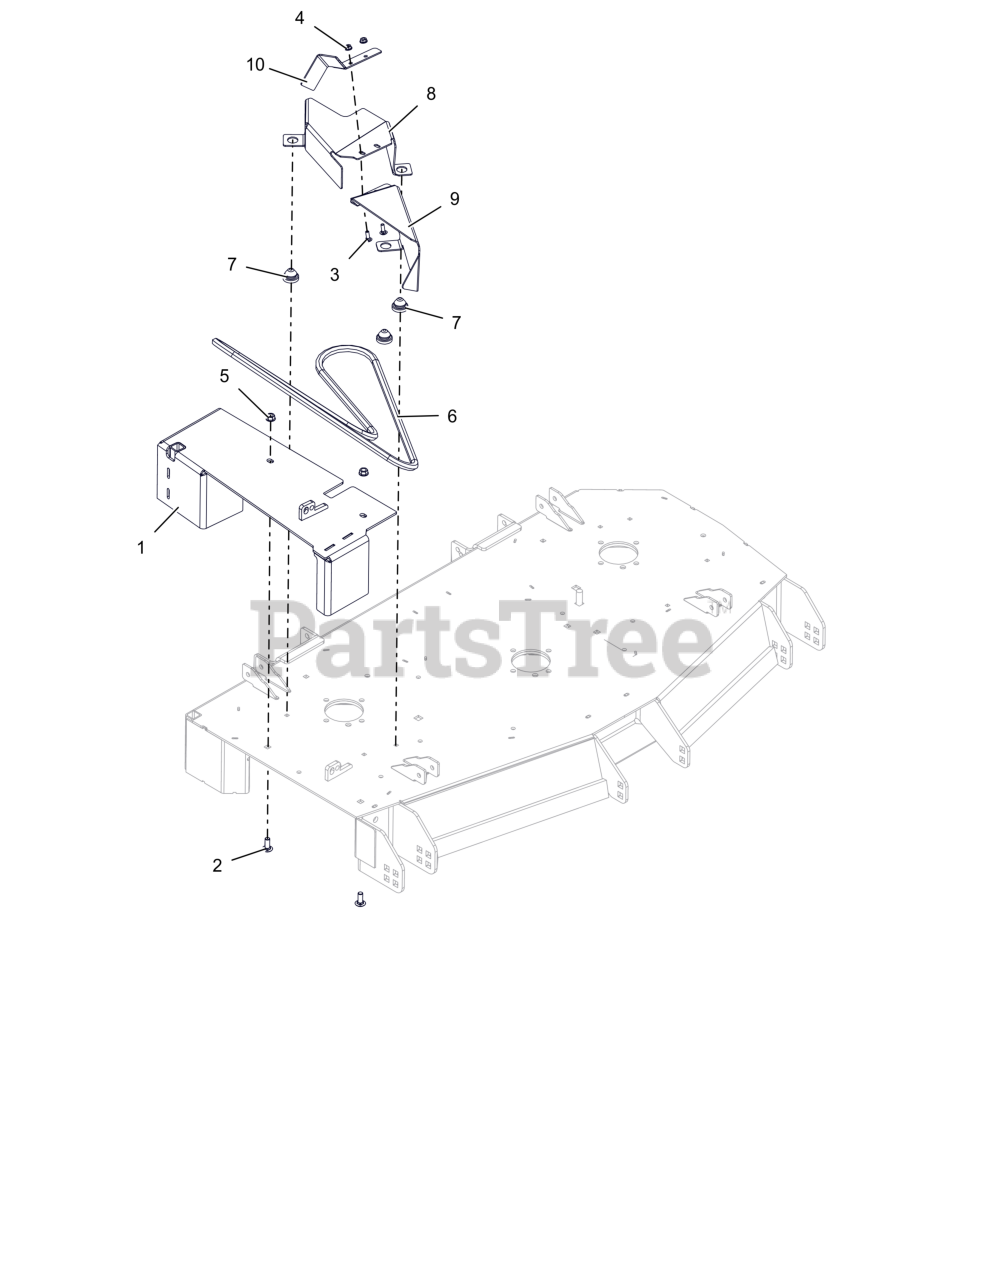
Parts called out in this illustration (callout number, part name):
1	WLDMT, BLOWER MOUNT - 48"
2	BLT,RHSSN .38-16X1.00 G5 ZCC
3	BLT, RHSN .25-20X.750 G5 ZCC
4	NUT-LK-CTR-FLG .25-20 ZC120
5	NUT-LK-CTR-FLG .375-16 GF ZCC
6	HEX BELT- HAA-WRAPPED
7	COUPLING, RUBBER PUSH-IN
8	COVER- RIGHT BAGGER BELT
9	COVER, UPPER, BAGGER BELT
10	COVER, UPPER BAGGER BELT
